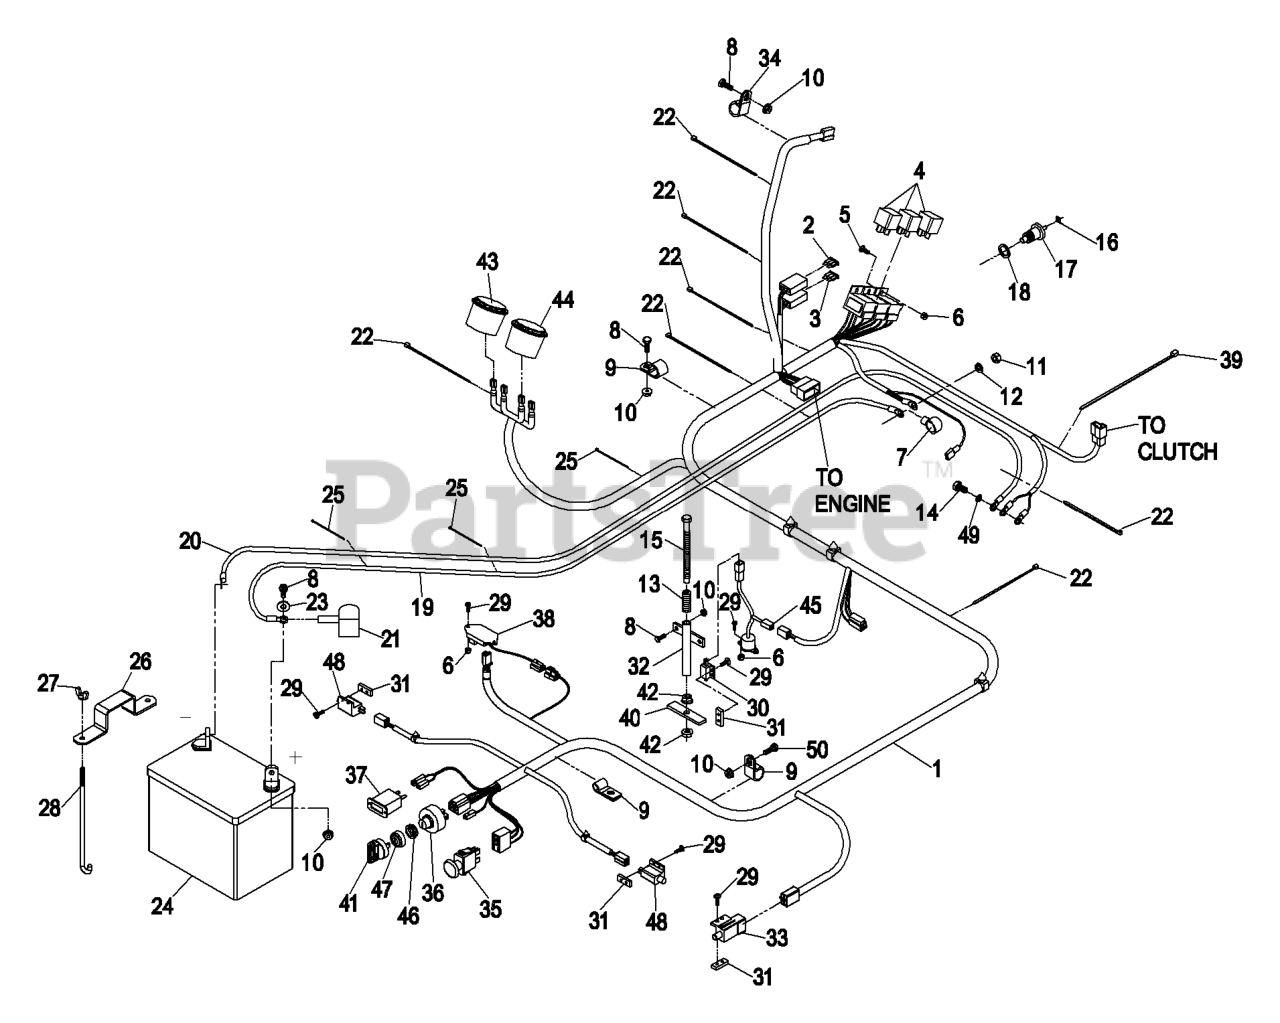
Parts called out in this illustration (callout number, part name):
1	CONTACT EXMARK SERVICE
2	FUSE-BLADE TYPE, 20 AMP
3	FUSE-BLADE TYPE, 30 AMP
6	NUT-LOCK, NI
7	INSULATOR-SOLENOID
8	SCREW-HH
9	CLIP-LOOM
11	NUT-HEX
12	WASHER-PLAIN
13	SPRING-SWITCH, SEAT
14	SCREW-HH
15	SCREW-HH
17	SENDER-TEMPERATURE
18	WASHER-ALUMINUM
20	WIRE-GROUND
22	TIE-PLASTIC
23	WASHER-FLAT
25	TIE-CABLE
27	WINGNUT
28	BOLT-HOLDDOWN
29	SCREW-PPH
30	SWITCH-CLOSED, NORMALLY
31	PLATE-TAPPED
34	CLIP-LOOM
37	METER-HOUR
38	MODULE-DELAY, SEAT
39	TIE-PLASTIC
40	PLATE-SWITCH, SEAT
41	KEY-IGNITION
43	GAUGE-VOLTMETER
44	GAUGE-TEMPERATURE
46	NUT-SWITCH, IGNITION
47	SEAL-SWITCH, IGNITION
48	SWITCH-OPEN, NORMALLY
49	WASHER-PLAIN
50	SCREW-HH
